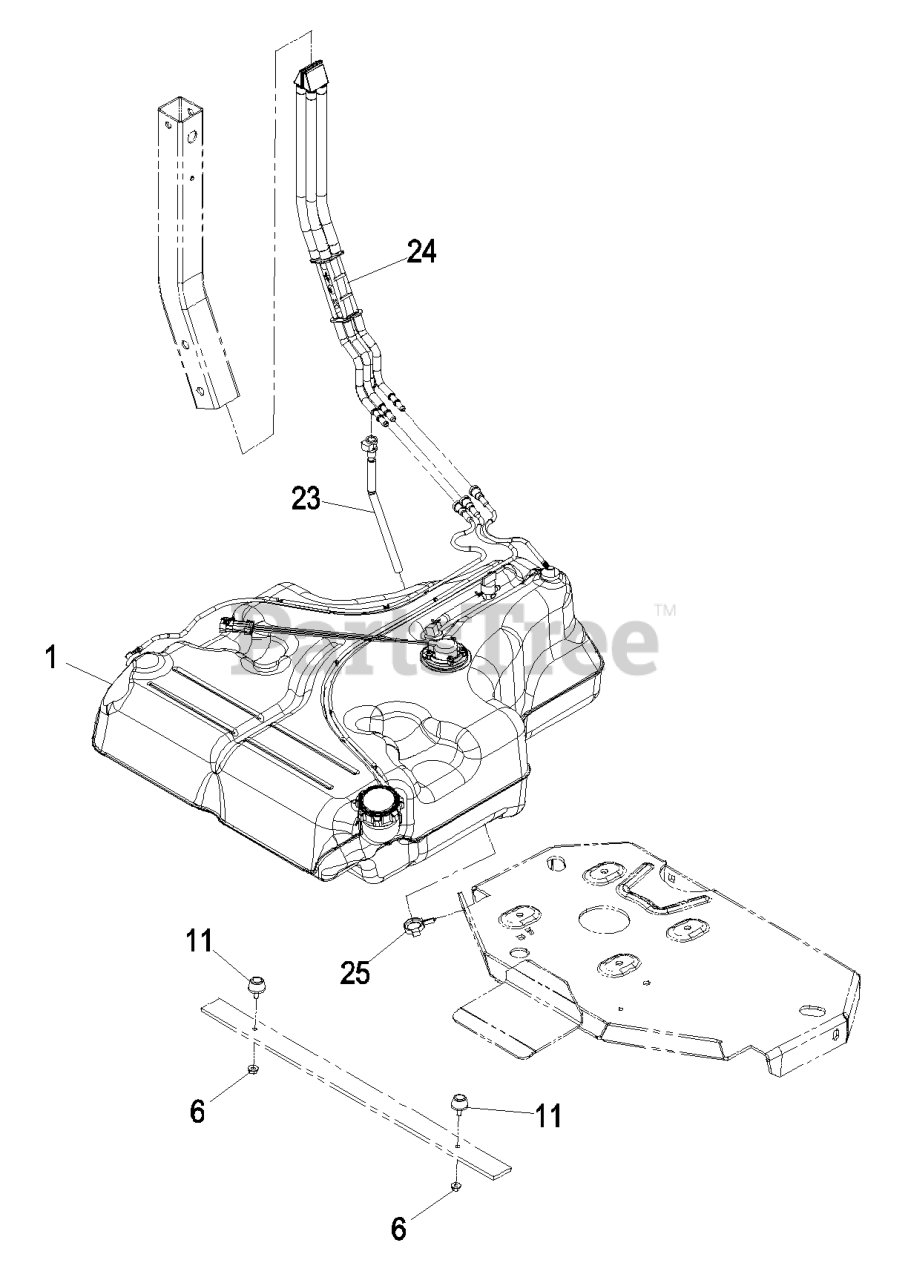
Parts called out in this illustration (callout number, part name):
11	BUMPER-RUBBER
23	TUBE-VENT, FUEL DRAIN
24	FUEL MANIFOLD VENT ASM
25	CLAMP-HOSE
